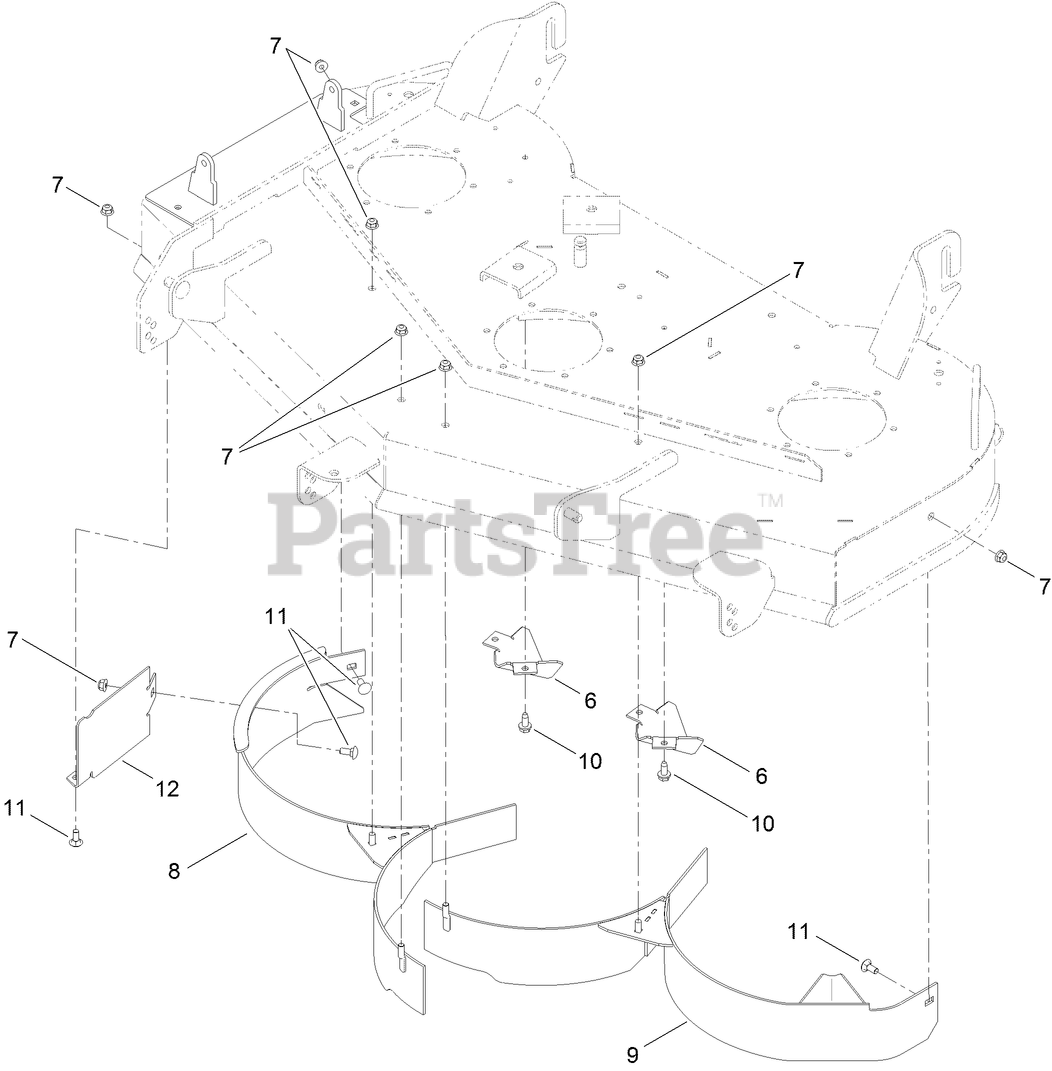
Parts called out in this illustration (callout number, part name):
6	KICKER-FLANGED
7	NUT-HF, NI
8	RH BAFFLE ASM
9	LH BAFFLE ASM
10	SCREW-HWHTF
11	BOLT-CARR
12	GUARD-BAFFLE
